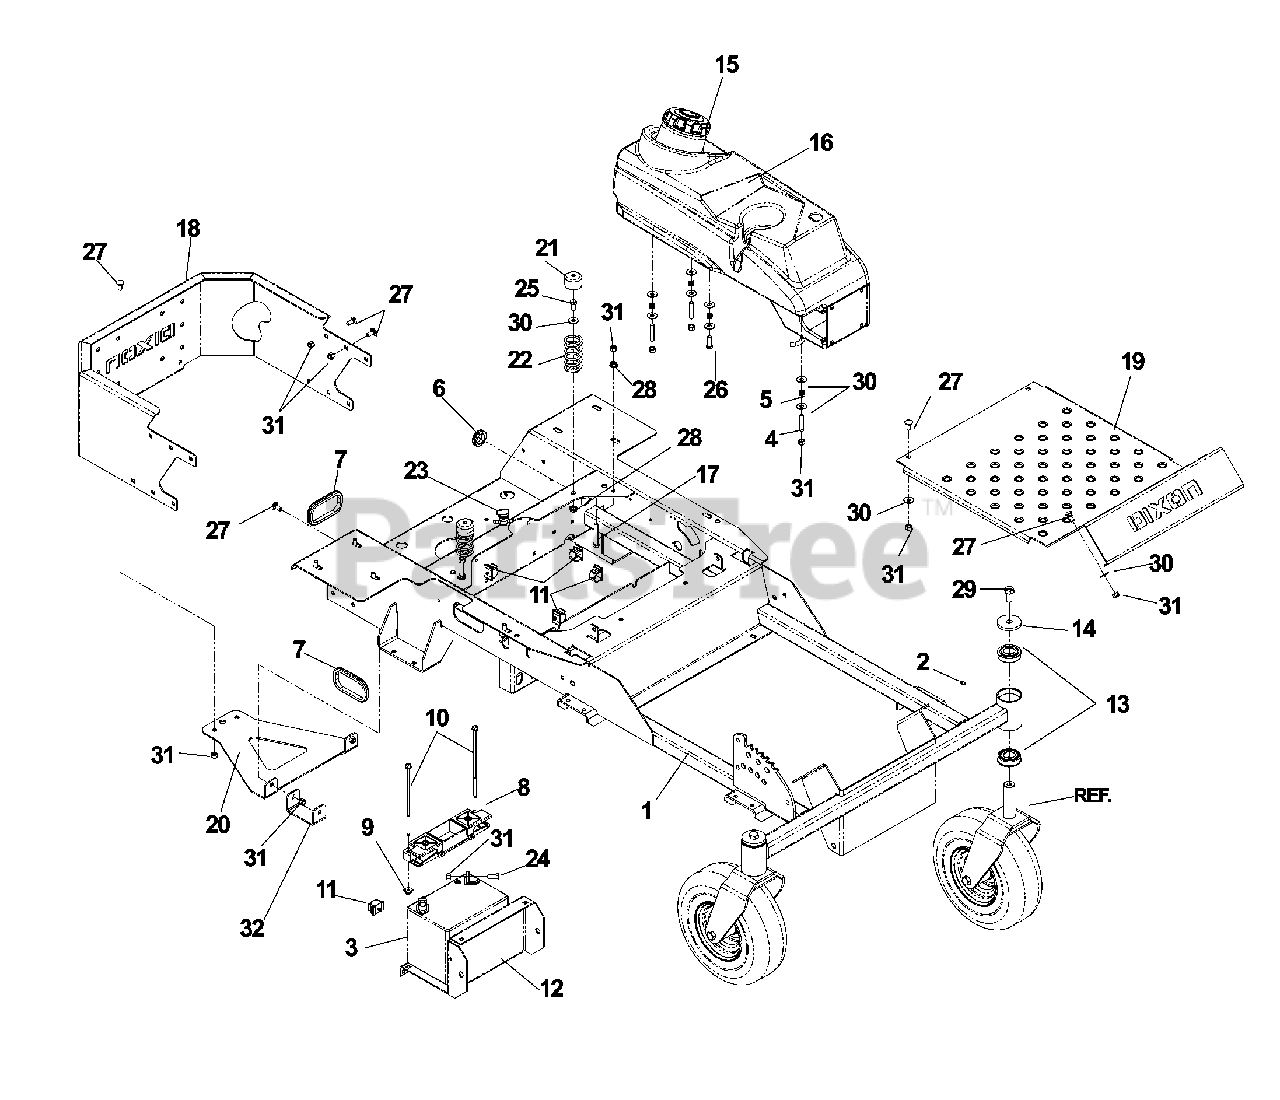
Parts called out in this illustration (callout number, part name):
3	BATTERY, 12 V 330 AMP TBR
4	STUD, 5/16C
6	RUBBER GROMMET
7	GROMMET
8	BATTERY HOLD DOWN
9	PUSH NUT-NYLON
10	BOLT - 1/4-20 X 7.5
11	PUSH-MOUNT WIRE CLIP
12	BATTERY TRAY
13	BEARING FLANGED
14	HEAVY WASHER
15	FUEL CAP ANTI-SPLASH
16	TANK, FUEL, LT
17	TAP BOLT 5/16C X 2 1/4
18	GUARD, REAR
19	FLOOR PAN WITH DECALS RAM
20	STRAP, REAR
21	SPRING CAP
22	SEAT SPRING
23	FUEL VALVE
24	HCS 5/16C X 3/4
25	SCREW 5/16C X 1 HEX CAP
26	HCS 5/16C X 1
27	BOLT 5/16C X 3/4" CARRIAGE
28	NUT 5/16C WHIZ
29	HHCS 1/2-13 X 1
30	WASHER 5/16 FLAT
31	NUT 5/16 NYLOC
